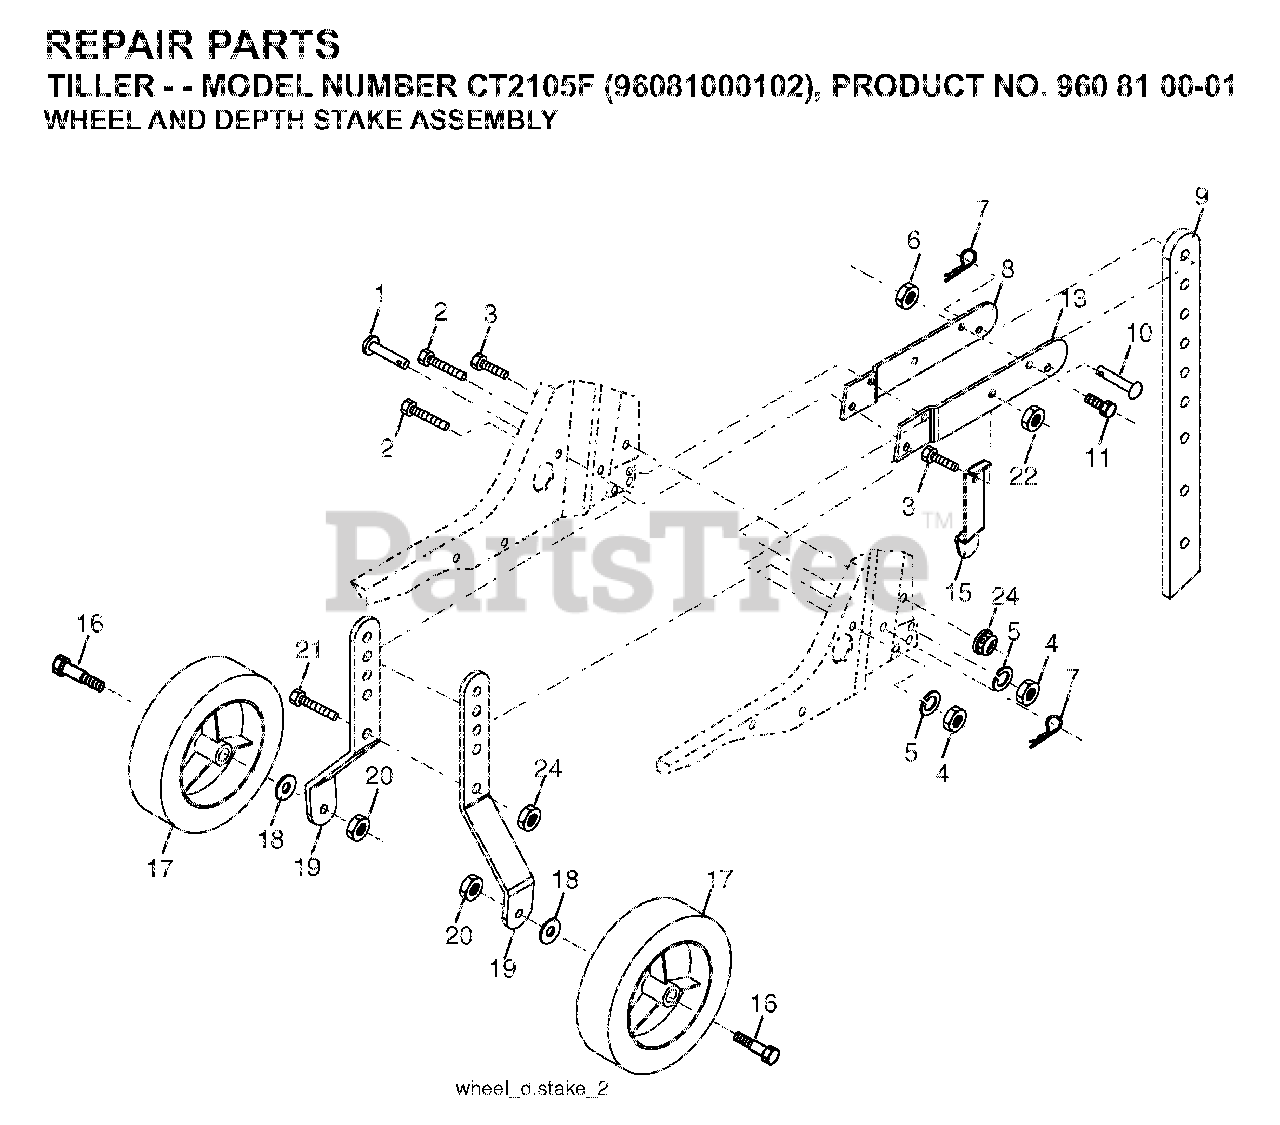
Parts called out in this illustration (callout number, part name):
1	PIN
2	BOLT
3	BOLT
4	NUT
5	LOCKWASHER
6	NUT
7	SPRING TI
8	SUPPORT.STAKE.RH.BLACK
9	RP STAKE.DEPTH.13.25.W/9HOLES
11	BOLT
16	BOLT.SHOULDER
18	WASHER
20	LOCKNUT
21	BOLT RB
22	NUT.71038.31-18.HEX.NYLOCK
24	LOCKNUT-FLANGE 5/16-18
